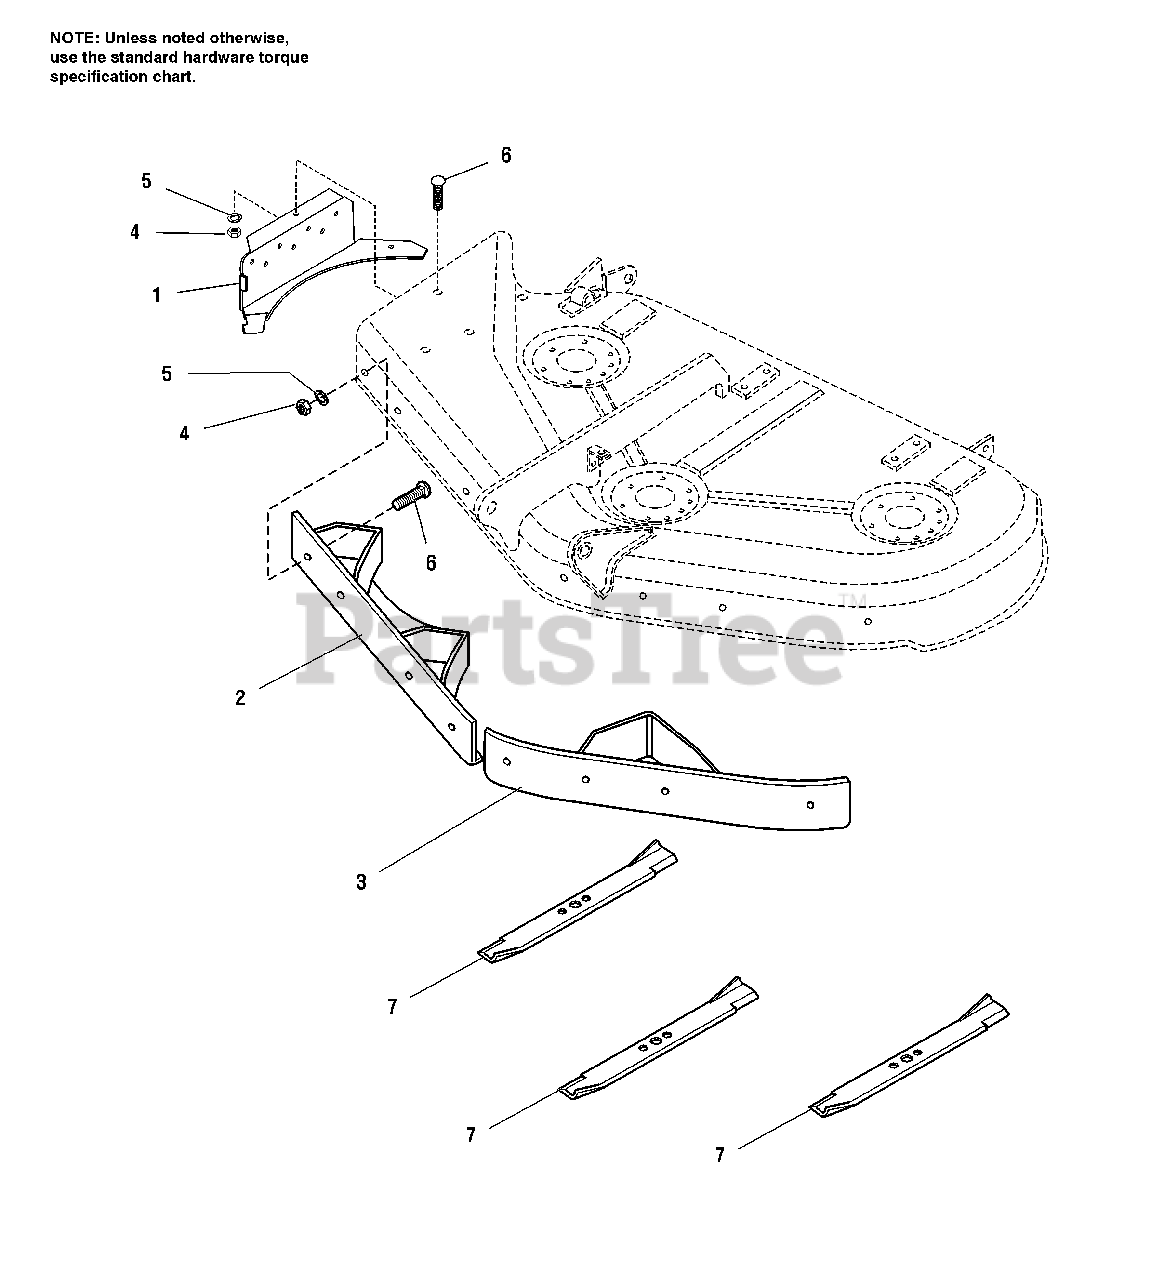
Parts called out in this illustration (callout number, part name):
1	PLATE, Discharge Closure
2	BAFFLE Assembly, RH 50"
3	BAFFLE Assembly, LH 50"
4	NUT, Hex 5/16-18
5	LOCK WASHER, 5/16
6	BOLT, Carriage 5/16-18 x 0.625
7	BLADE, Mulch for 50"
